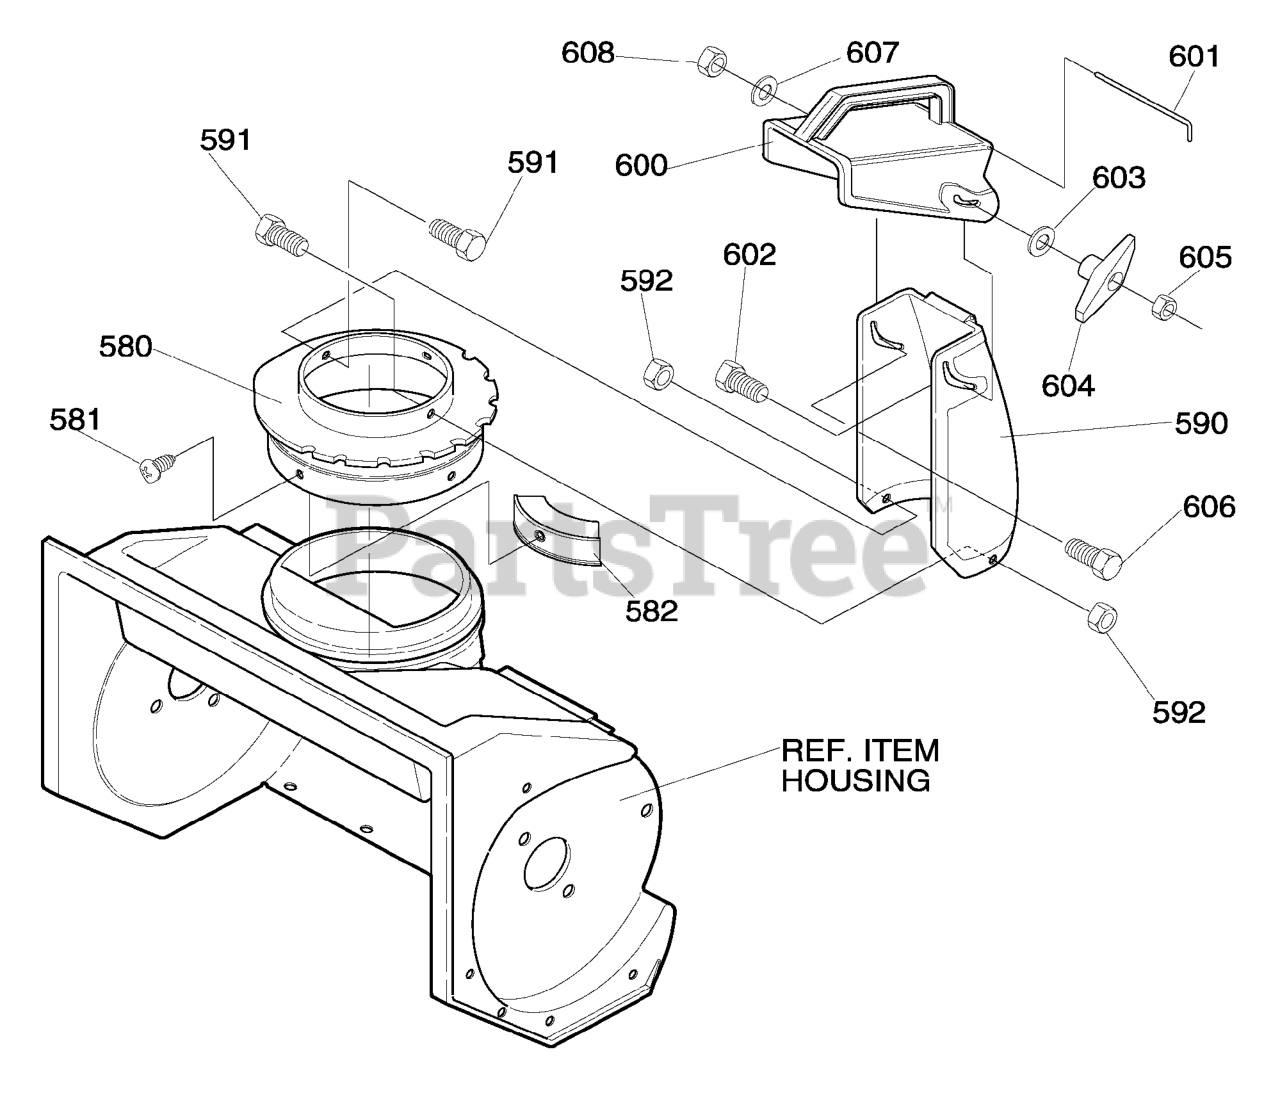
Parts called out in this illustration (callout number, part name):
580	RING, CHUTE
581	SCREW, 1/4-20 x .50
582	GUIDE, CHUTE
590	LOWER CHUTE
591	SCREW, 1/4-20 x .50
592	NUT, 1/4-20
600	UPPER CHUTE
601	WIRE HINGE
602	BOLT, 5/16-18 x 1.25
603	FLATWASHER
604	T KNOB
605	NUT, 5/16-18
606	SCREW, 5/16-18 x 0.75 SL
607	FLATWASHER
608	NUT, 5/16-18
